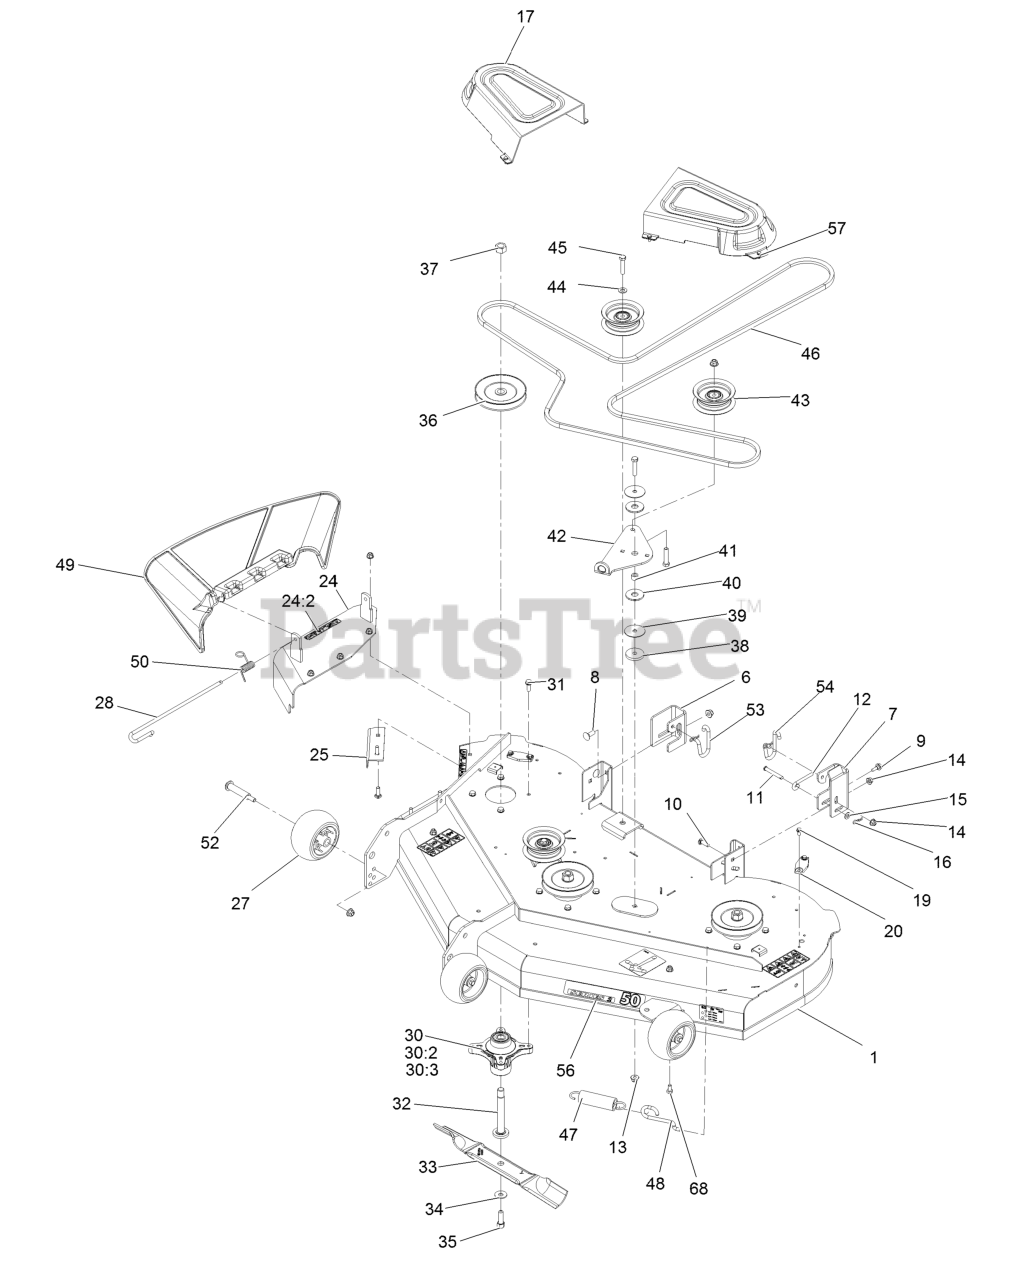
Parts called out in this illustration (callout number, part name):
1	DECK AND DECAL ASM
6	BRACKET-HANGER, RH
7	BRACKET-HANGER, LH
8	BOLT-CARR
9	SCREW-SHOULDER,HWH
10	SCREW-CARR
11	PIN-CLEVIS
12	ROD-LEVEL, DECK
13	NUT-HF, NI
14	NUT-HF, NI
15	WASHER-PLAIN
16	PIN-COTTER
17	COVER-BELT
19	SCREW-HWH
20	COVER-WASHOUT PORT
24	COVER ASM W/DECAL
24:2	DECAL-DANGER
25	BAFFLE-CUTOFF
27	ROLLER-SCALP, ANTI
28	PIN-CHUTE
30	SPINDLE ASM
30:3	BEARING-BALL
31	SCREW-TAPTITE
32	SHAFT-SPINDLE
33	BLADE-HI LIFT
34	WASHER-BELLEVILLE
35	SCREW-HH
37	NUT-HEX
38	WASHER-PLAIN
40	WASHER-FRICTION, COMPOSIT
42	ARM-IDLER
44	WASHER-FLAT
45	SCREW-HH
46	V-BELT
47	SPRING-EXTENSION
48	HOOK-RETURN, SPRING
49	DEFLECTOR-DISCHARGE
50	SPRING-TORSION
52	BOLT-SHOULDER
53	LINK-RETENTION, DECK (RH)
54	LINK-RETENTION, DECK (LH)
56	DECAL-SERIES 2 - 50
57	SCREW-TAPTITE
68	SCREW-HH
